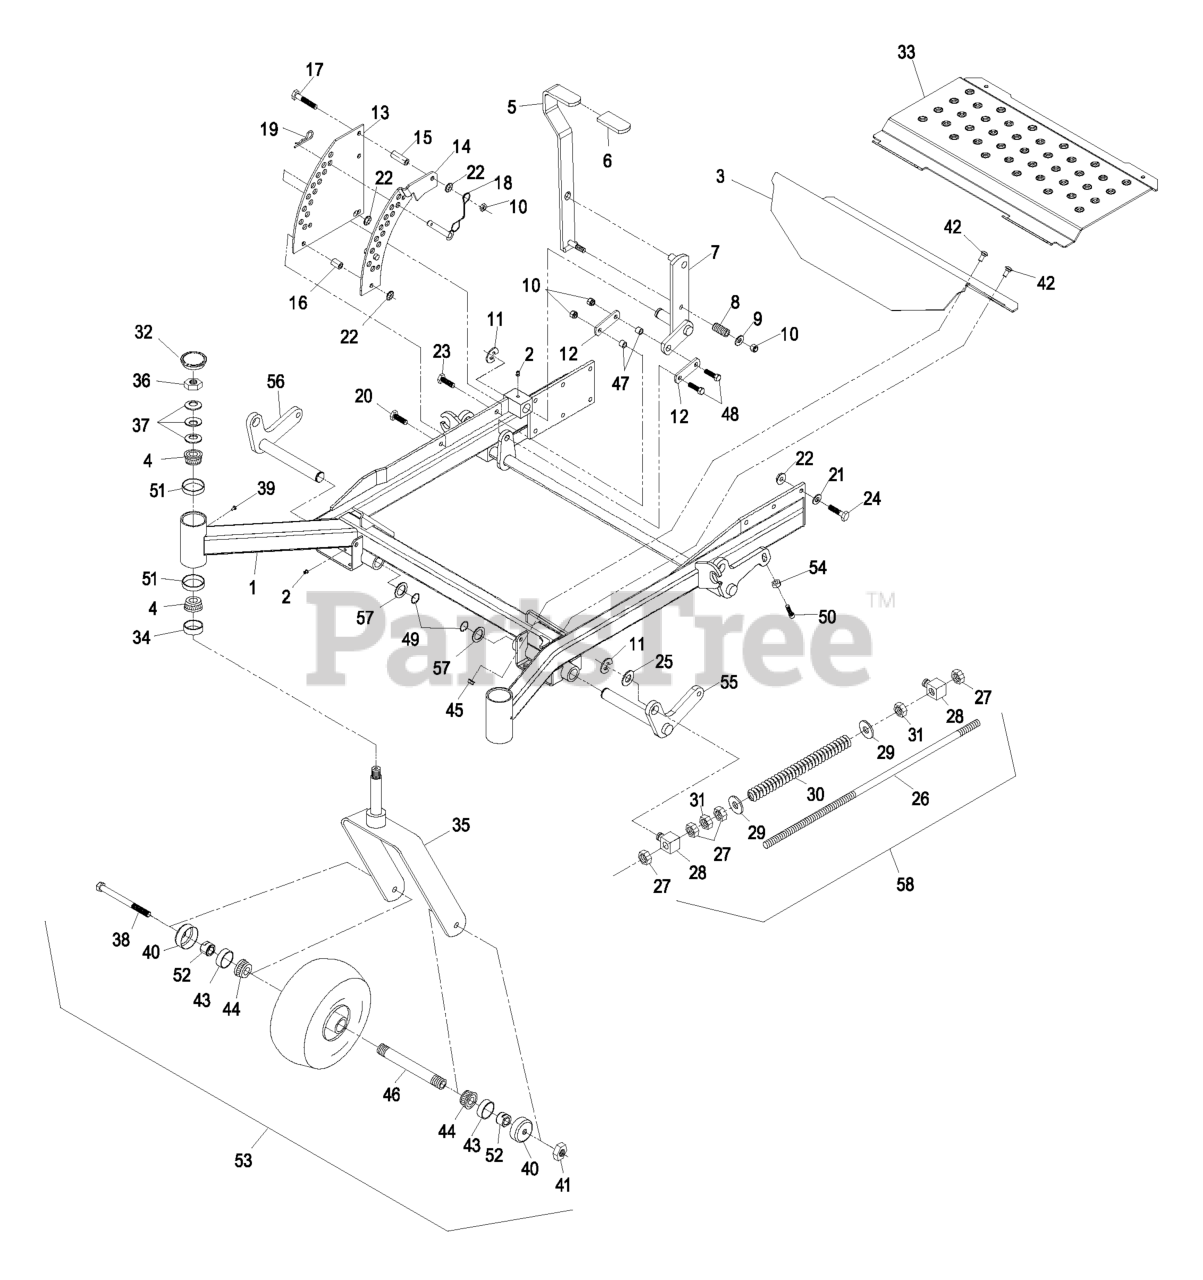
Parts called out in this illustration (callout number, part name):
1	KIT,FRONT FRAME LZ 52
2	FITTING-GREASE
3	ASM, FLOORPAN FRONT W/DEC
4	Cone-Bearing Tapered Roller
5	LIFT LEVER/GRIP ASM
6	GRIP-LEVER, LIFT
7	ARM-LIFT, DECK
8	SPRING-COMPRESSION
9	WASHER-FLAT
10	NUT-LOCK, NI
11	RING-RETAINING, EXT
12	ARM-LIFT, DECK
13	PLATE-LIFT, DECK
14	Plate Wldmt, Deck Lift
15	BUSHING-LEVER, LIFT
16	BUSHING-LEVER, LIFT
17	SCREW-HH
18	PIN-HITCH (W/LANYARD)
19	PIN-COTTER
20	SCREW-HH
21	WASHER-BELLEVILLE
22	NUT-HHF, WHIZ
23	SCREW-HH
24	SCREW-HH
25	WASHER-FLAT
26	ROD-LIFT, DECK
27	NUT-HEX
28	SWIVEL-DECK MOUNT, REAR
29	WASHER-FLAT
30	SPRING-SUPPORT, DECK
31	NUT-JAM
32	CAP-GREASE
33	ASM, FLOORPAN LIFTOUT W/D
34	SEAL-GREASE
36	NUT-LOCK, NI
37	WASHER-BELLVILLE
38	SCREW-HH
40	GUARD-SEAL
41	NUT-LOCK, NI
42	BOLT-CARR
43	SEAL-CASTER
44	BEARING-CONE, TAPERED ROLLER
47	BUSHING
48	SCREW-HH
49	RING-RETAINING
50	SCREW-HSH
51	CUP-BEARING
52	SPACER-NUT
53	ASM, WHEEL AND TIRE W/ AX
54	NUT-JAM
55	WLD, FRONT LIFT SHAFT - L
56	WLD,FRONT LIFT SHAFT RH
57	WASHER-SPACER
58	FRONT FRAME SPRING ASM
